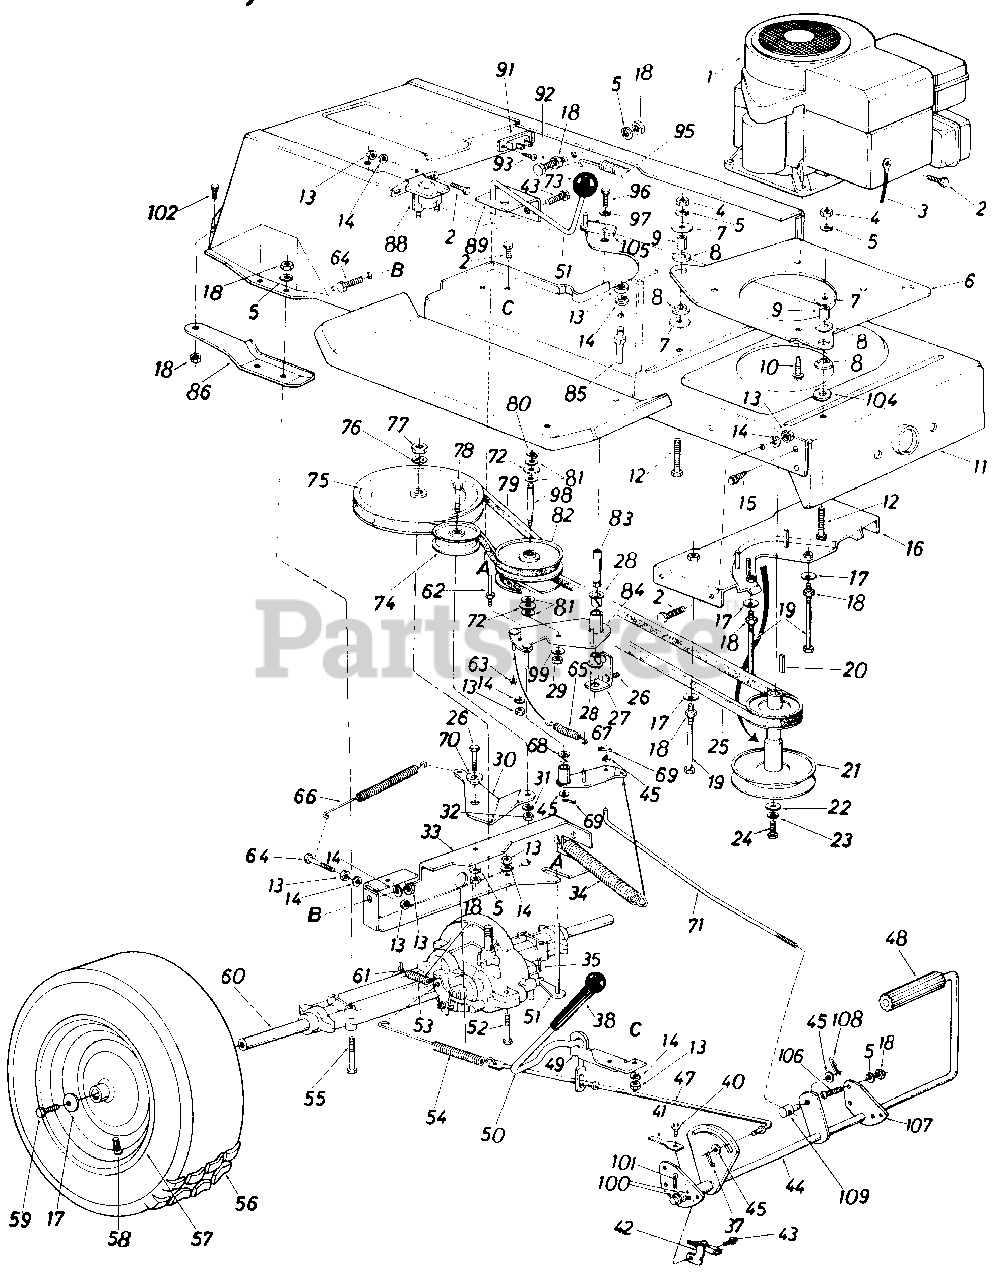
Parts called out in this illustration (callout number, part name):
1	Engine
2	Hex Bolt 1/4-20 x .62" Lg.
3	Electric Ground Wire
4	Hex Nut 5/16-24 Thd.
5	L-Wash. 5/16" I.D.
6	Engine Mounting Plate
7	Fl-Wash. .320" I.D. x 1.25"
8	Engine Mounting Grommet
9	Spacer
10	Hex Bolt 3/8-16 x 1.25" Lg.
11	Lower Frame Ass'y.
12	Hex Bolt 5/16-24 x 1.25"
13	Hex Nut 1/4-20 Thd.
14	L-Wash. 1/4" I.D.
15	Hex Wash. Hd. AB-Tap Scr. 5/16" x.75" Lg.
16	Belt Guard Brkt. Ass'y.
17	Bell-Wash. .345" I.D. x .88"
18	Hex Nut 5/16-18 Thd.
19	Hex Bolt 5l16-18 x 4.00"
20	Sq. Key 1/4" x 1/4" x 2.00"
21	Engine Pulley
22	Fl-Wash. 7116" I.D. x 1.25"
23	L-Wash. 7116" I.D.
24	Hex Bolt 7/16-20 x 1.50" Lg.
25	Variable-Speed Belt .715 x 53" Lg.
26	Hex Bolt 5/16-18 x .50" Lg.
27	Bearing Shaft Bracket
28	Flanged Nyliner Brg. 518" I.D. x .88" Lg.
29	Hex Nut 3/8-24 Thd.
30	Idler Bracket
31	L-Wash. 3/8" I.D.
32	Hex Nut 3/8-24 Thd.
33	Transaxle Support Brkt.
34	Ext. Spring .94" O.D. x 6.7
35	Cotter Pin 1/8" Dia. x 1.0"
37	Cotter Pin 3/32" Dia. x 1.0"
38	Grip-Black
40	Hex Wash. Hd. Self-Tap Scr. 1/4-20 x .50" Lg.
41	Switch Actuator
42	Safety Switch
43	Hex Wash. Hd. AB-Tap Scr. 1/4 x.62" Lg.
44	Clutch & Brake Pedal Ass'y.
45	Fl-Wash.
47	Brake Rod
48	Foot Pad
49	Brake Lever Bracket
50	Hill Holder Brake Handle
51	Shift Lever Ass'y.
52	Hex Bolt 1/4-28 x 1.75" Lg.
53	Ext. Spring .38" O.D. x 2.5"
54	Ext. Spring .59" O.D. x 7.08"
55	Hex Bolt 5/16-18 x 2.50"
56	Wheel Ass'y. Comp.
57	Wheel Rim Only
58	Air Valve
59	Hex Bolt 5/16-24 x .75" Lg.*
60	Transaxle Cornplete
61	Brake Return Spring Anchor
62	Belt Guard Pin 1/4-20 Thd.
63	Cap Speed Nut 1/4" Dia.
64	Hex Bolt 1/4-20 x .62" Lg. Grade 5
65	Ext. Spring .50" Dia.
66	Ext. Spring .62" O.D. x 6.12"
67	Variable Speed Torque Brkt. Ass'y.
68	Flanged Bearing
69	Cotter Pin 3132" Dia.
70	Shoulder Spacer .500" Dia. x.27" Lg.
71	Speed Control Link
72	Truss Bearing .56 Dia. x 1 .25 "
73	Ball Knob
74	Fl-Idler Pulley 3.25" x 1.0"
75	.50" "V"-Pulley 8.0" O.D. x.501" I.D.
76	L-Wash. 1/2" I.D.
77	Hex Jam Nut 1/2-20 Thd.
78	Hex Bolt 3/8-24 x 1.50" Lg.
79	Variable Speed Belt .715 x 44" Lg.
80	Snap Ring .56" Dia.
81	Fl-Wash.
82	Variable Speed Pulley Ass'y. 5" O.D.
83	Bearing Shaft
84	Variable Speed Brkt. Ass'y.
85	Belt Guard Pin 1/4" Dia. x 1.68" Lg.
86	Transaxle Support Brkt.-R.H.
88	Solenoid
89	Shift Lever Bracket
91	Circuit Breaker
92	Hex Bolt 5/16-18 x 1.25" Lg.
93	Truss Hd. Phil. Scr. #10 x 1/2" Lg
95	Ext. Spring .99" O.D. x 11.0"
96	Hex Bolt 3/8-24 x .75" Lg.
97	Bell-Wash. .38" I.D. x .88"
98	Shaft .56" Dia. x 3.875" Lg.
99	Bell-Wash. .39" I.D. x 1.12"
100	Fl-Wash.
101	Cotter Pin
102	Hex Wash. Hd. Scr. 5/16-18 x.62" Lg.
104	Fl-Wash. .32" I.D. x 1.25"
105	Belt Guard
106	Truss Mach. Scr. 5/16-18 x .75" Lg.
107	Pedal Bracket
108	Hairpin Cotter 118" Dia.
109	Ferrule
